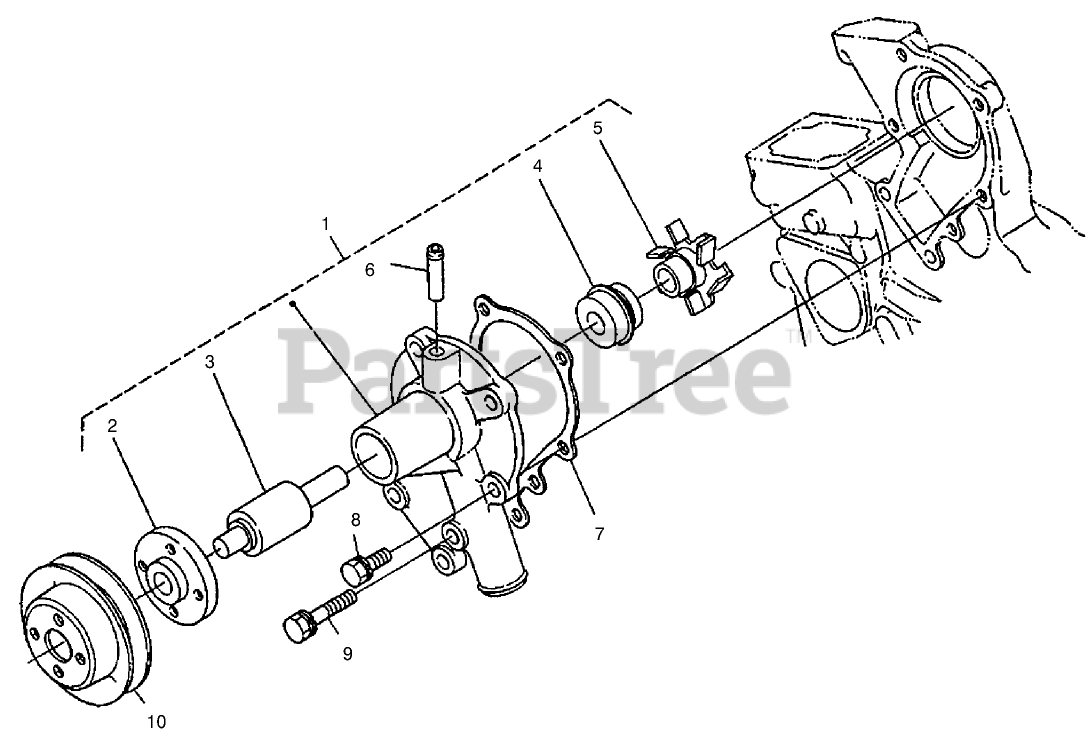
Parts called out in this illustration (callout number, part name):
1	WATER PUMP ASM
2	FLANGE-PUMP, WATER
3	BEARING-BALL
4	WATER PUMP SEAL ASM
5	IMPELLER-PUMP, WATER
6	PIPE-RETURN, WATER
7	GASKET-PUMP, WATER
10	PULLEY-FAN
